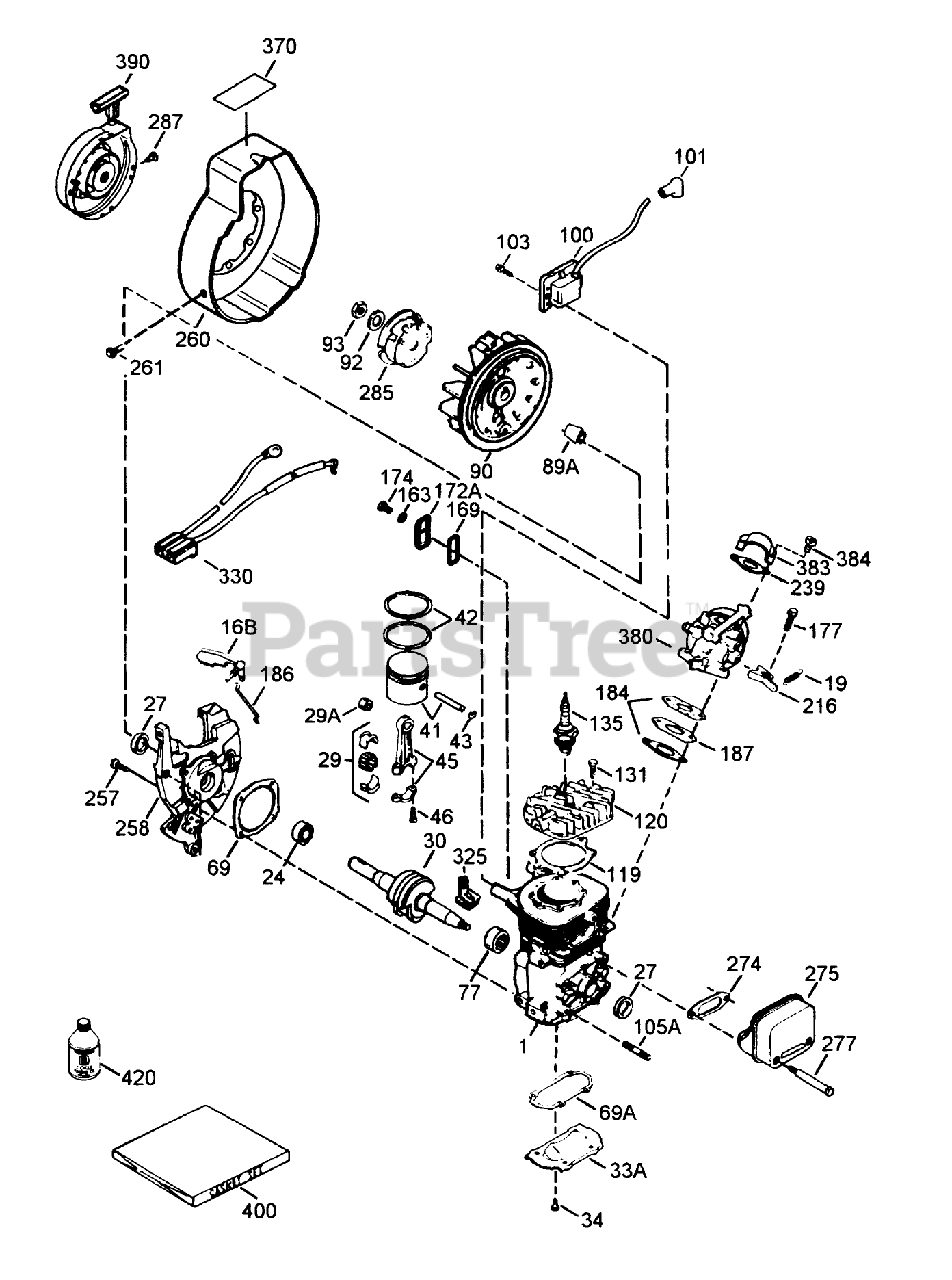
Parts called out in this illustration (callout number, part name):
1	Block Ass-y-Cylinder (Order short block if replacement is required)
16B	Vane-Air
19	Spring-Extention
24	Bearing-Ball
27	Seal-Oil
29	Needle Bearing and Liner Set (37 Needles)
29A	Bearing-Cartridge
30	Crankshaft
33A	Plate-Cover
34	Screw (T-25, 10-24 x 1/2)
41	Piston (Incl. Ref. #43)
42	Ring Set
43	Ring-Retaning
45	Rod Assy.-Connecting (Incl. Ref. #3, 3A 3B)
46	Bolt-Rod, Connecting
69	Gasket-Cover, Cylinder
69A	Gasket-Plate, Cover
77	Bearing-Cartridge
89A	Blade (20 inch)
90	Flywheel
92	Washer-Belleville
93	Nut-Flywheel
100	Solid State
101	Cover-Spark Plug
103	Screw
119	Gasket-Head, Cylinder
120	Head-Cylinder
131	Screw (T-30, 1/4-20 x 3/4)
135	Spark Plug-Resistor (R C J 8Y)
163	Washer
169	Cover-Compression, Release
172A	Cover-Release, Compression
174	Screw (T-25, 10-24 x 1/2)
177	Screw (5/32 Allen, 1/4-20 x 1)
184	Gasket-Carburetor
186	Governor-Link
187	Spacer
216	Lever-Adjusting, Rpm
239	2060A77 WIZARD ROTA
257	Screw (T-30, 1/4-20 x 5/8)
258	Base Assy.-Blower Housing (Incl. Ref. #10)
260	Blower Housing
261	Screw (1/4-20 x 1/2)
274	Gasket-Exhaust
275	Muffler (Incl. Ref. #274 277)
277	Screw (1/4-20 x 2-3/4)
285	Cup-Starter
287	Screw (8-32 x 21/64)
325A	Clip-Wire
330	Harness-Wire
370	Decal-Warning
380	Carburetor (Incl. Ref. #184A)
383	Baffle-Carburetor
384	Screw
390	Rewind Starter
400	Gasket Set
420	2-Cycle Oil (8oz)
